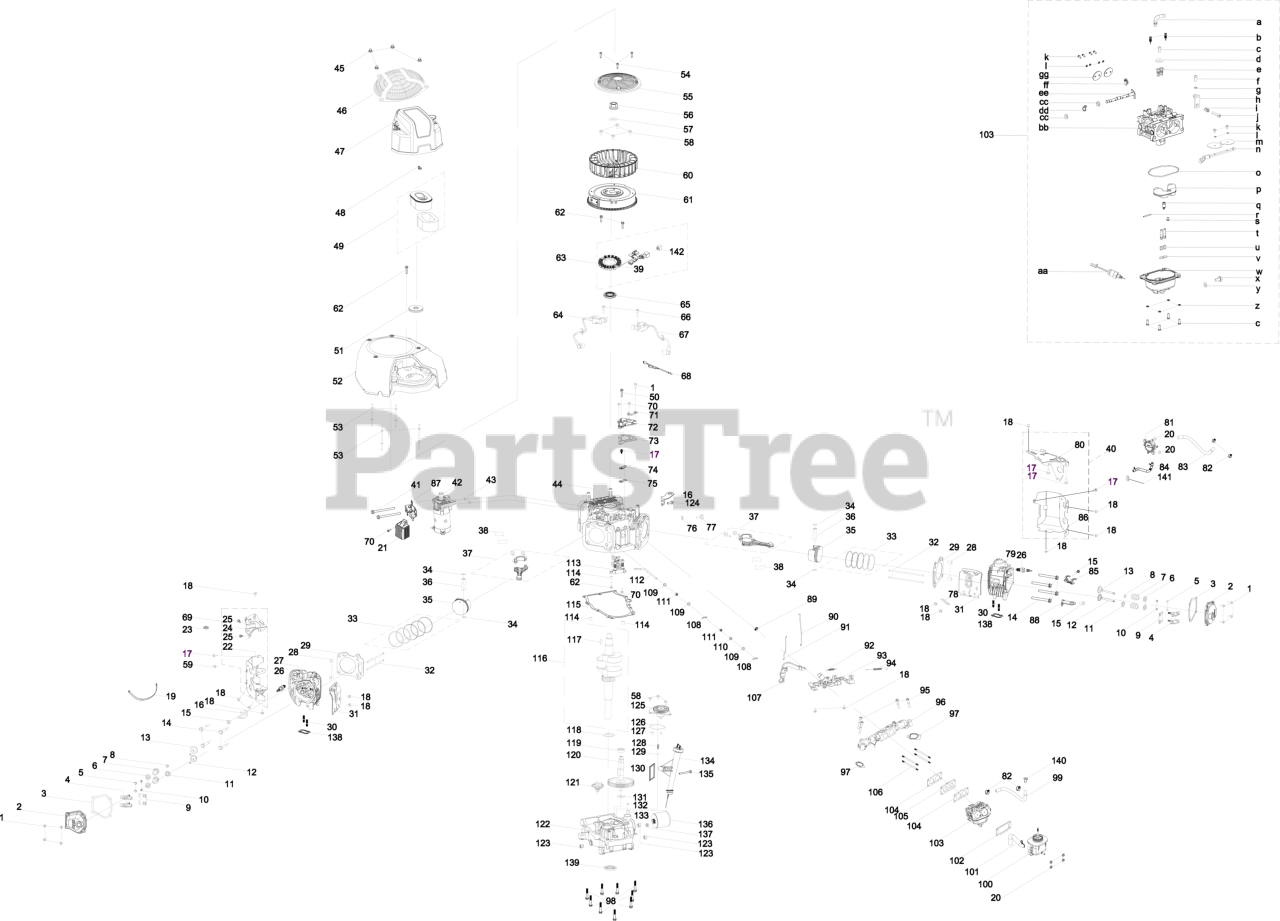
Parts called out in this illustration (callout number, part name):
1	BOLT M6 x 22
2	VALVE COVER
3	VALVE COVER GASKET
4	ROCKER ARM ASSEMBLY
5	EXHAUST VALVE ADJUSTER
6	VALVE SPRING SEAT
7	VALVE SPRING
8	INTAKE VALVE SEAL
9	PUSH ROD GUIDE
10	VALVE CAP
11	VALVE SPRING RETAINER
12	EXHAUST VALVE
13	INTAKE VALVE
14	HEX HEAD BOLT - M10X1.25X87
15	HEX HEAD BOLT M8X16
16	LIFT HOOK BRACKET - LH
17	BOLT M6-1 x 10 GR8.8
18	BOLT M6-1 x 12 GR8.8
19	CABLE TIE 3x150
20	HEX NUT
21	REGULATOR ASSEMBLY
22	CYLINDER HEAD BAFFLE
23	HEAT SHIELD GROMMET
24	FLYWHEEL SHROUD - LH
25	HEX HEAD SCREW M6X10
26	SPARK PLUG (F6RTC/RN11YC/BPR6ES)
27	CYLINDER HEAD - LH
28	DOWEL PIN 12x20
29	CYLINDER HEAD GASKET
30	STUD M8 x 36
31	SHROUD
32	PUSH ROD
33	PISTON RIN SET
34	PISTON PIN SNAP RING
35	PISTON ASSEMBLY
36	PISTON PIN
37	CONNECTING ROD
38	CONNETING ROS BEARING
39	CHARGING COIL
40	SHROUD ASSEMBLY (RH)
41	HEX HEAD BOLT M8X110
42	STARTER MOTOR
43	DOWEL PIN
44	CRANKCASE
45	ACORN NUT M6-1
46	SHROUD FAN COVER
47	AIR FILTER COVER ASSEMBLY
48	WING NUT
49	AIR FILTER ELEMENT
50	BOLT-M6-1 x 28 GR8.8
52	BLOWER HOUSING
53	STUD - M6-1.0X69.8X117
54	BOLT 5.5 x 25
55	DEBRIS SHIELD
56	NUT M20 x 1.5
57	WASHER 20.5 x 5 x 40
58	BOLT M6-1 x 18 GR8.8
59	WIRE SUPPORT CLAMP
60	COOLING FAN
61	FLYWHEEL
62	BOLT M6-1 x 25 GR8.8
63	CHARGING COIL
64	IGNITION MODULE (LH)
65	OIL SEAL 38 x 58 x 8
66	BOLT-M6-1 x 30 GR8.8
67	IGNITION MODULE (RH)
68	WIRE HARNESS
69	SHROUD ASSEMBLY (LH)
70	BOLT M6 x 16
71	FLYWHEEL GUARD BRACKET
72	BEATHER COVER
73	BREATHER COVER GASKET
74	BREATHER REED BRACKET
75	BREATHER REED ASSEMBLY
76	WASHER 20.5X1.5X18
77	HEX HEAD BOLT M10X1X10
79	CYLINDER HEAD - RH
80	SHROUD (RH)
81	FUEL PUMP
82	CARBURETOR HOSE CLAMP
83	FUEL HOSE
84	FUEL LINE
85	MOUNTING BRACKET
86	CYLINDER HEAD BAFFLE
87	STARTER RELAY SUPPORT
88	REAR LIFT BRACKET
89	CHOKE LINKAGE LOCK CLAMP
90	THROTTLE LINKAGE
91	CHOKE LEVER
92	GOVERNOR SPRING
93	GOVERNOR GEAR BRACKET ASSEMBLY
94	GOVERNOR SPRING
95	SCREW - M8X50
96	INTAKE MANIFOLD
97	INTAKE MANIFOLD GASKET 9Q78
98	HEX HEAD FLANGE BOLT M8X48
99	FUEL LINE 6.3 x 12.5 x 470
100	INTAKE MANIFOLD
101	BREATHER HOSE
102	AIR FILTER HOUSING GASKET
103	CARBURETOR
104	CARBURETOR GASKET
105	INSULATOR
106	STUD M6-1 x 105
107	GOVERNOR LEVER
108	GOVERNOR SHAFT CLIP
109	FLAT WASHER 8.5X15.8X2
110	GOVERNOR SEAL
111	NEEDLE BEARING 8X12X10
112	GOVERNOR ARM ROD
113	ROACKER ARM
114	PIN 8X12
115	CRANKCASE GASKET
116	CRANKSHAFT ASSEMBLY
117	WOODRUFF KEY
118	WASHER - 38.5X1.0X54
119	CAMSHAFT BEARING
120	CAMSHAFT ASSEMBLY
121	GOVERNOR GEAR
122	CRANKCASE COVER
123	ENGINE PLUG 3/8 NPT
124	HEX HEAD SCREW M8X16
125	OIL PUMP ASSEMBLY
126	OIL PUMP GASKET
127	DOWEL PIN
128	OIL PUMP SPRING
129	OIL PUMP STEEL BALL
130	OIL PUMP SCREEN
131	THRUST WASHER 17.4X25.9X1.0
132	O-RING 13.2X2.65
133	CRANKCASE OIL PASSAGE PIN
134	DIPSTICK
135	SCREW M6-1:50:CL5.
136	ENGINE OIL FILTER
137	SCREW JOINT OIL FILTER ADAPTER
138	EXHAUST GASKET
139	OIL SEAL 38 x 58 x 8
141	GROMMET
